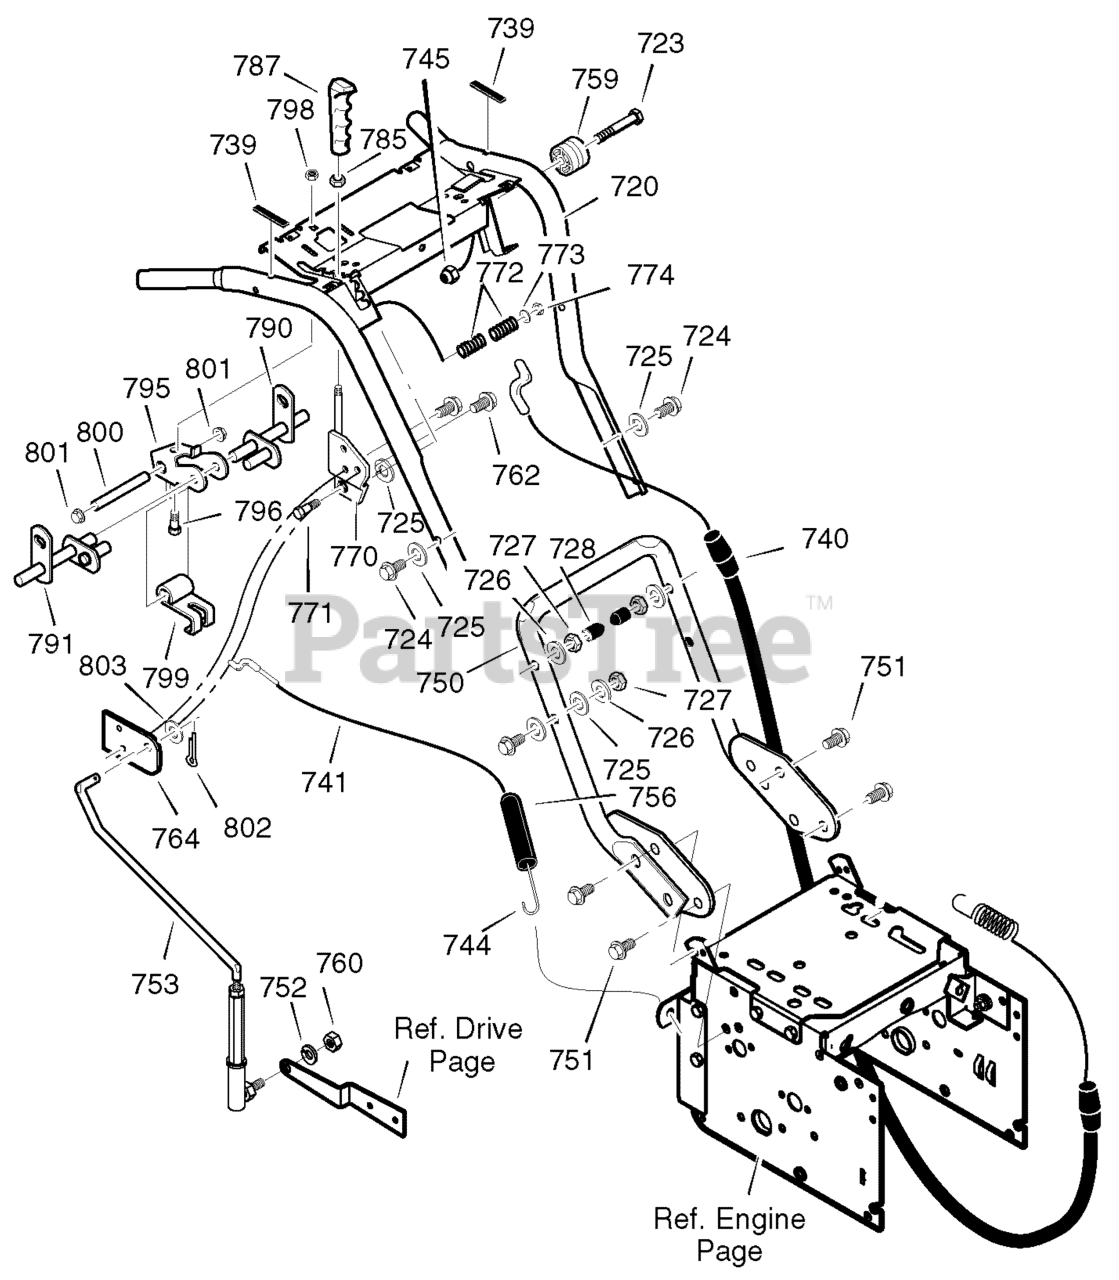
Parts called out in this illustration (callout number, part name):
720	ASSY., HANDLE
724	SCREW
725	WASHER, FLAT
726	WASHER
728	STOP, PLASTIC
739	BUMPER
740	CABLE, DRIVE
741	CABLE, AUGER
744	SPRING, CLUTCH
745	NUT, HEX
750	HANDLE, LOWER
751	SCREW
753	ASSEMBLY, ROD
756	BOOT, CABLE
759	SPOOL, CABLE
760	NUT, 5/16-24
762	SCREW 1/4-20X0.63
764	BRKT, CONTROL
770	BRACKET, SHIFT
771	SCREW
772	SPRING
773	WASHER, FLAT
774	NUT, HEX, 3/8-16
785	NUT, HEX, 3/8-16
787	KNOB, SHIFT
790	ROD, ASSY LH
791	ROD, ASSY RH
795	BRACKET, CAM
796	SCREW
798	NUT, NYLOCK
799	CAM LOCK
800	PIN, SPRING PIVOT
801	NUT, PUSH ON
802	PIN, COTTER
803	FLATWASHER
